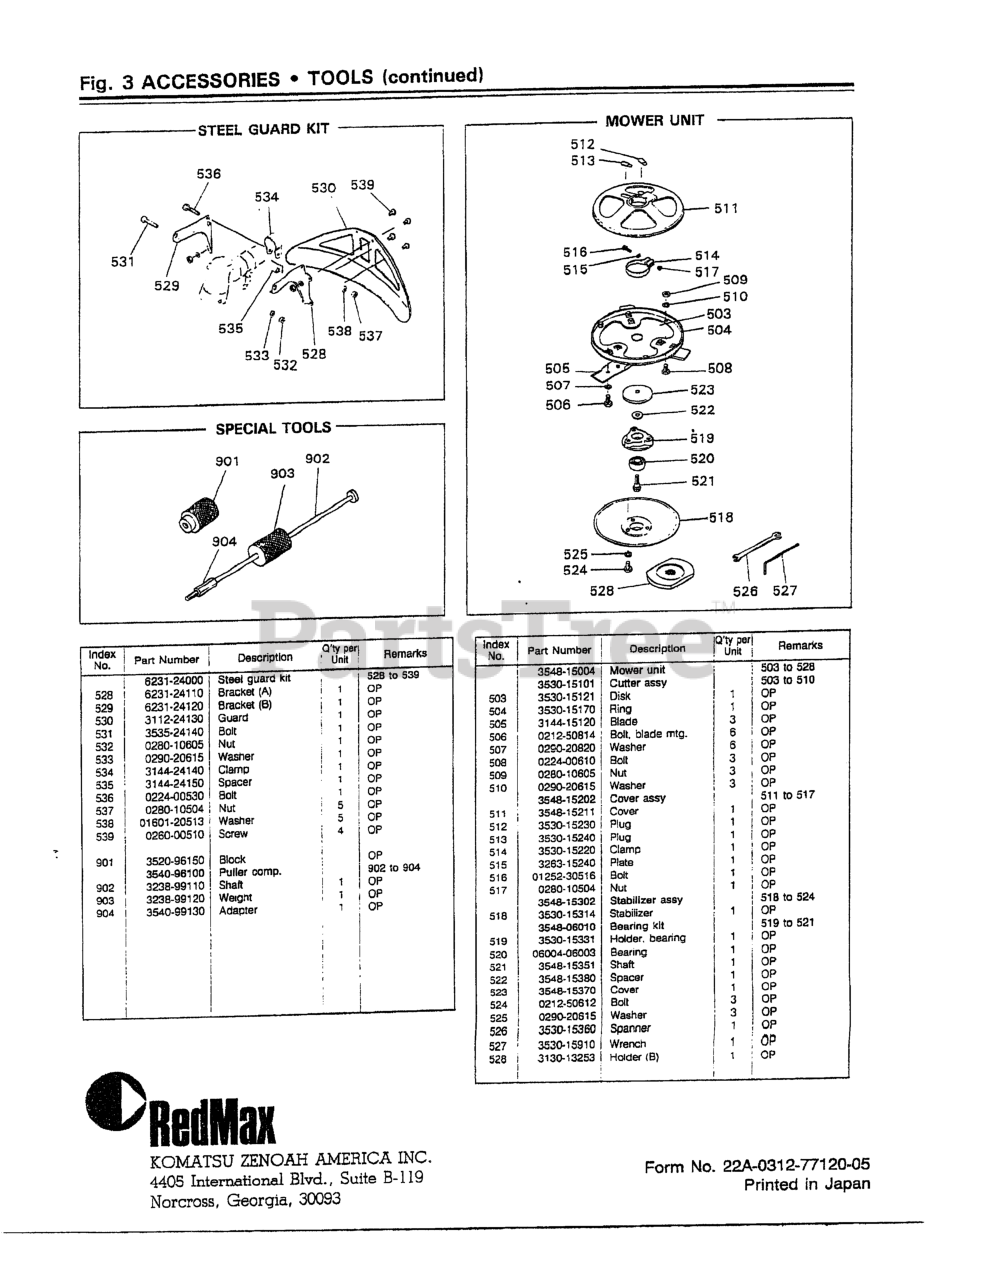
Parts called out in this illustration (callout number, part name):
506	BOLT, BLADE MTG.
507	WASHER, M8 x 20
508	BOLT, M6 x 10
509	NUT, M6 X 5
510	WASHER, M6 X 15
516	BOLT, M5 X 16
517	NUT, M5 X 4
518	STABILIZER
519	BEARING CASE
525	WASHER, M6 X 15
532	NUT, M6 X 5
533	WASHER, M6 X 15
536	BOLT, M5 x 30
537	NUT, M5 X 4
538	WASHER, SPRING M4 x 1.3
901	BLOCK (TOOL)
902	SHAFT (TOOL)
904	ADAPTER (TOOL)
